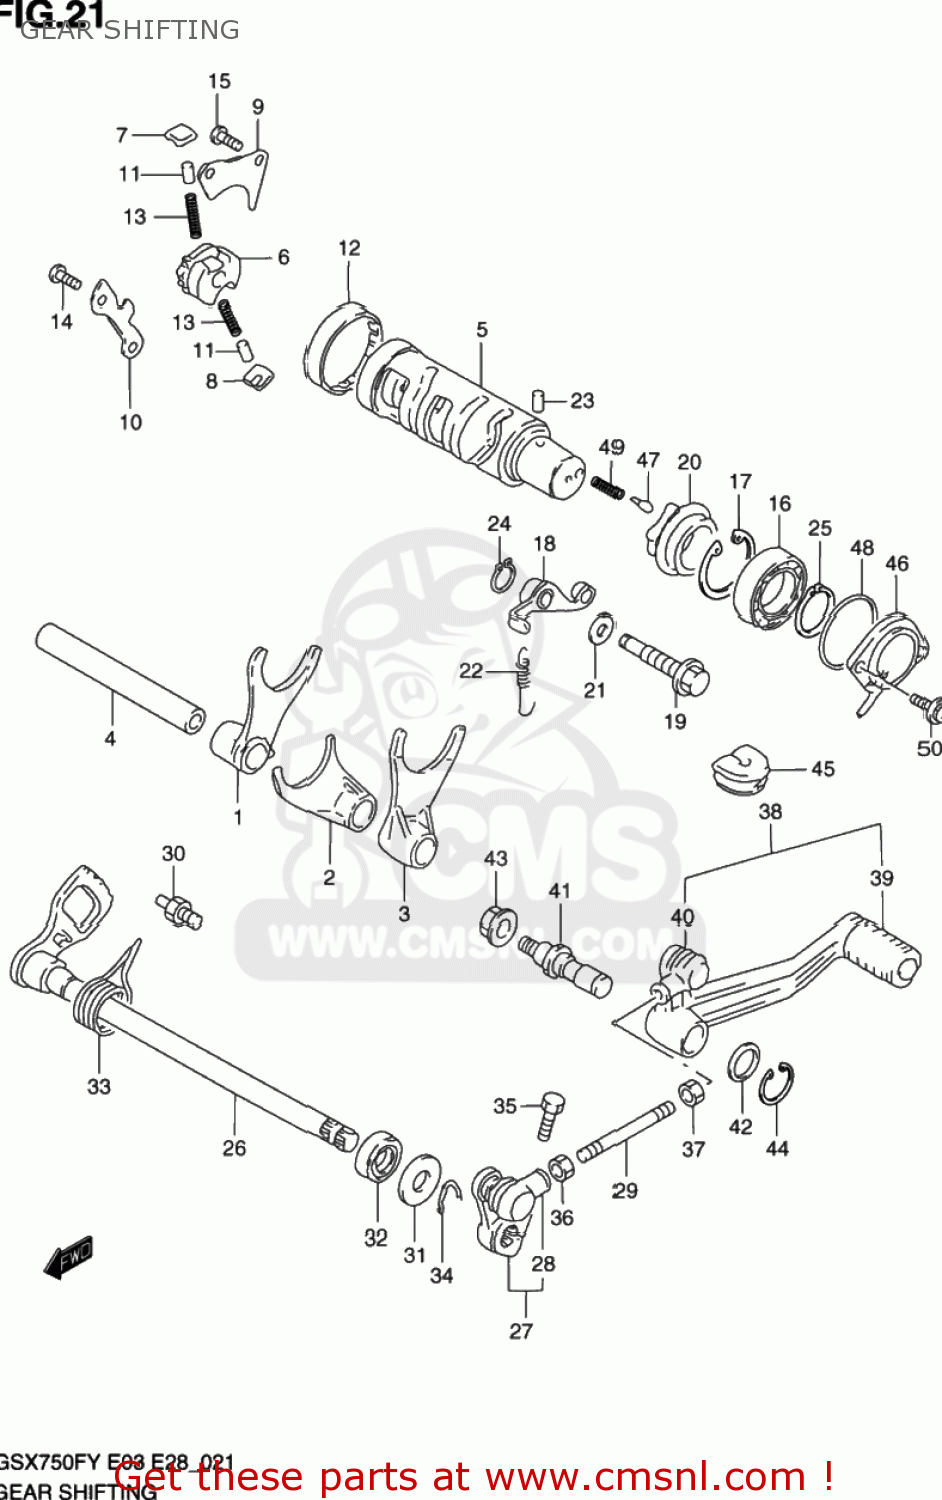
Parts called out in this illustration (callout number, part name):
1	FORK,GEAR SHIFT NO.1
2	FORK,GEAR SHIFT NO.2
3	FORK,GEAR SHIFT NO.3
4	SHAFT,GEAR SHIFT FORK(L:128)
5	CAM,GEAR SHIFT
6	GEAR,GEAR SHIFT CAM DRIVEN
7	PAWL,GEAR SHIFT NO.1
8	PAWL,GEAR SHIFT NO.2
9	LIFTER,GEAR SHIFT PAWL
10	GUIDE,GEAR SHIFT CAM
11	PIN(5X8)
12	BEARING(43X49X12)
13	SPRING
14	SCREW
15	SCREW
16	BEARING
17	CIRCLIP
18	STOPPER,GEAR SHIFT CAM
19	SHAFT,GEAR SHIFT CAM STOPPER
20	PLATE,STOPPER
21	GASKET(10X14X3.6) (NAS)
22	SPRING
23	PIN
24	CIRCLIP
25	CIRCLIP
26	SHAFT,GEAR SHIFT
27	ARM,GEAR SHIFT LINK
28	COVER,DUST
29	ROD,GEAR SHIFT LINK
30	STOPPER,GEAR SHIFT CAM
31	WASHER (12.5X26X1.6)
32	OIL SEAL
33	SPRING
34	CIRCLIP,12 MM
35	BOLT
36	NUT
37	NUT
38	LEVER ASSY,GEAR SHIFT
39	RUBBER,GEAR SHIFT PEDAL
40	COVER,DUST
41	SHAFT,GEAR SHIFT LEVER
42	WASHER(12.5X20X1)
43	NUT
44	CIRCLIP,12 MM
45	GROMMET,LEADWIRE
46	BASE ASSY,GEAR SHIFT TERMINAL
47	PIN(5X15.5)
48	O RING(D:2.4,ID:35.5)
49	SPRING
50	SCREW
